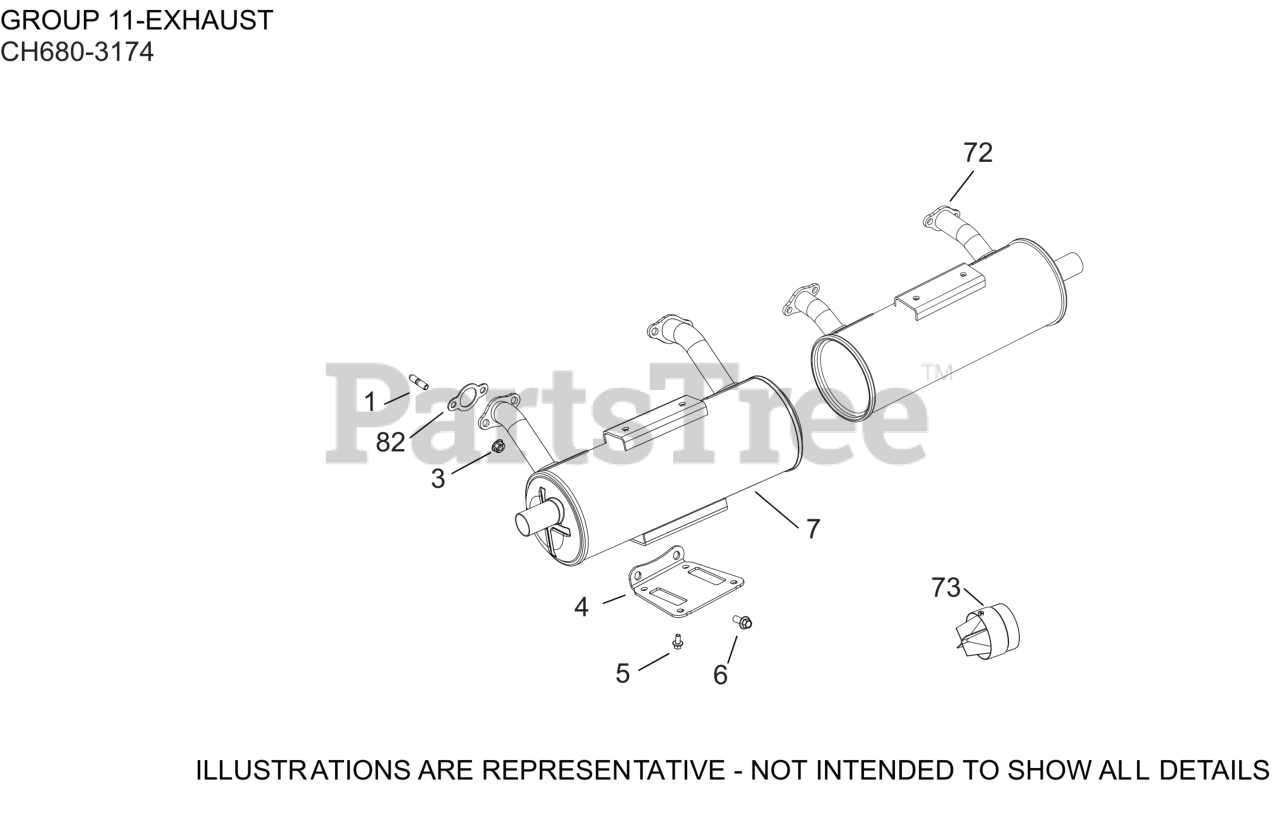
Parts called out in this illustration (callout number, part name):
1	STUD, METRIC EXHAUST
3	NUT, FLG M8X1.25
4	BRACKET, MUFFLER
5	SCREW, FLG M6X1.0X12
6	SCREW, FLG M8X1.25X20
7	KIT, MUFFLER
73	ARRESTOR, SPARK
82	GASKET, EXHAUST MANIFOLD
